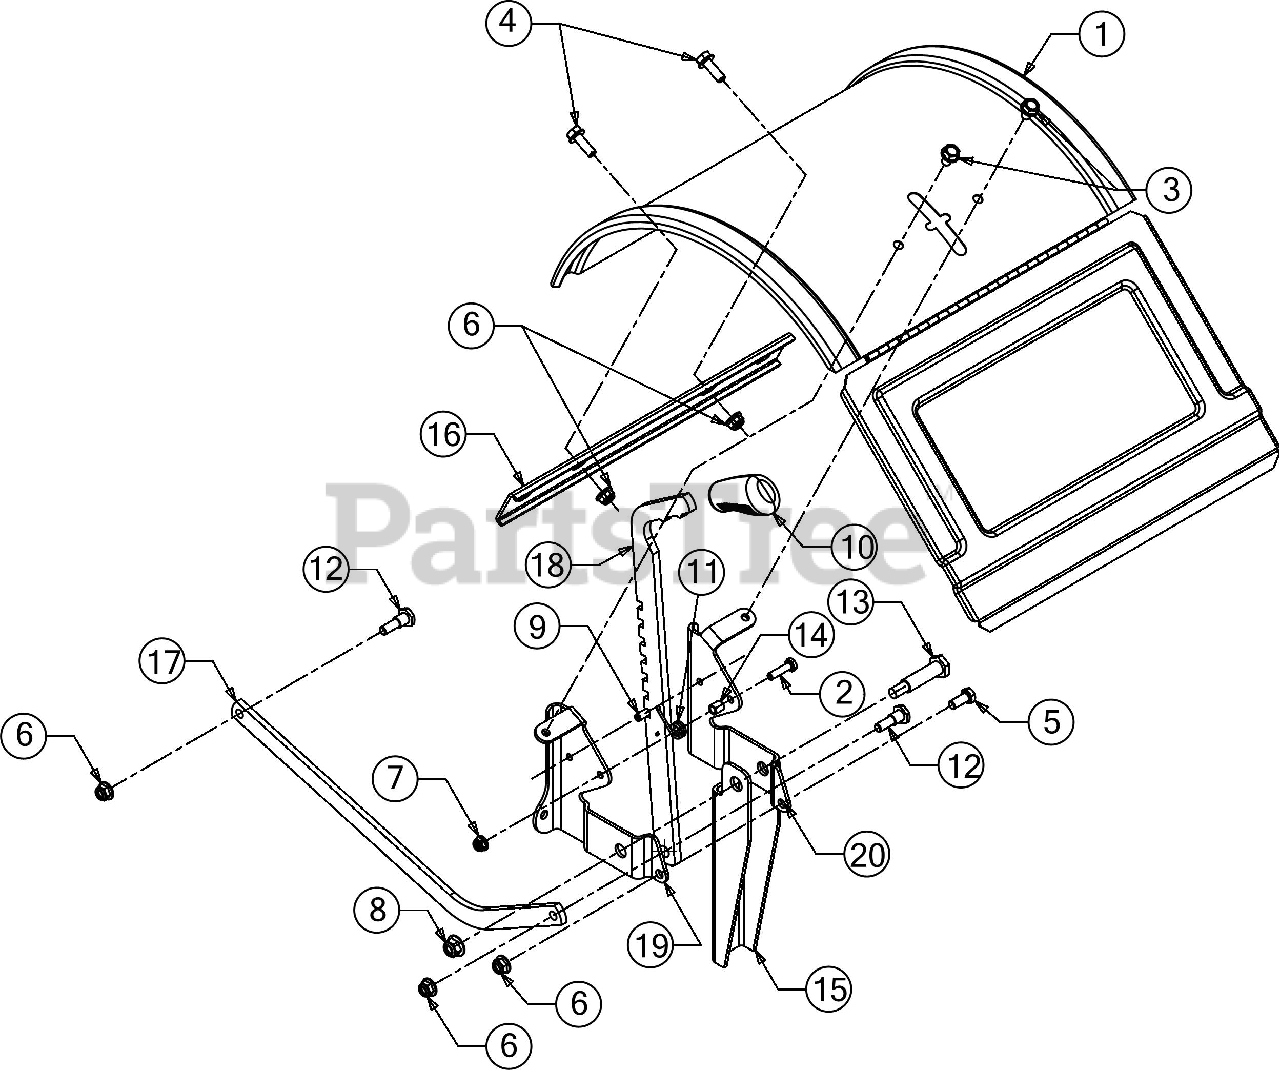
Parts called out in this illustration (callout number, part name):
1	TINE SHIELD ASSEMBLY
2	SCREW 1/4-20 X1.00 GR5
3	SCREW 5/16-18 x .625
4	SCREW 5/16-18 x .875 GR5
5	SCREW 5/16-18 x .75 GR5
6	FLANGE LOCK NUT 5/16-18
7	FLANGE LOCK NUT
9	SPRING PIN 1/4 x 1.00
11	TORSION SPRING
12	SHOULDER SCREW
13	SHOULDER BOLT .498 x 1.635:3/8-16
14	ROUND SPACER
15	REVERSE STOP ARM
16	SUPPORT BRACKET
17	DEPTH DRAG BAR
19	TAIL BRACKET (LH)
20	TAIL BRACKET (RH)
